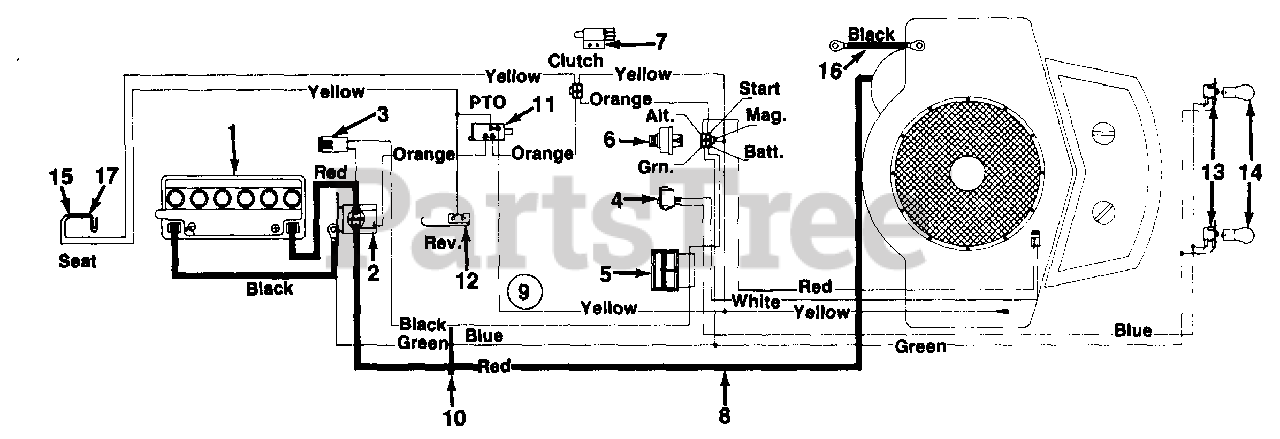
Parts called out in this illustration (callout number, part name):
1	Battery
2	Solenoid
3	Fuse 7.5 Amps
4	Light Switch
5	Ammeter
6	Ignition Switch
7	Safety Switch (Clutch)
8	Electric Wire 32.5" Lg. (B&S)
9	Wire Harness w/o Ammeter
10	Cable Tie
11	Safety Switch (Deck)
12	Safety Switch (Reverse)
13	Socket
14	Bulb (Headlight)
15	Safety Switch (Seat)
16	Ground Wire 7.5" Lg.
17	Safety Switch (Seat)
